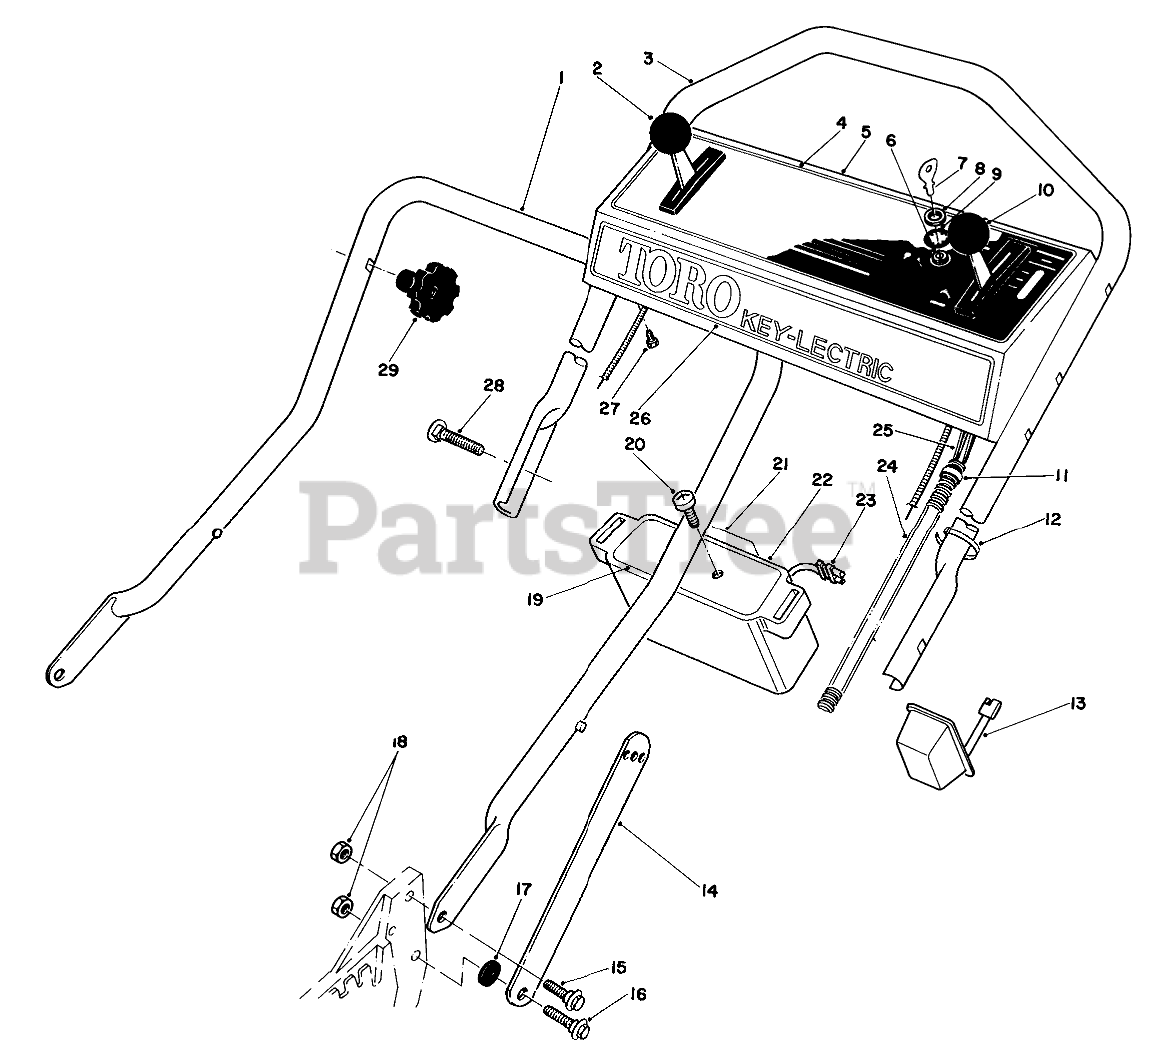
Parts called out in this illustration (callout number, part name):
1	Handle-Lower
2	GROUND SPEED CONTROL
3	Handle-Upper
4	Decal-Instruction Panel
5	Control Panel (Incl Ref. #4)
6	STARTER SWITCH ASM
7	Key
8	NUT-HH
9	WASHER-TOOTH, INTERNAL
10	SERVICE THROTTLE CONTRO
11	FITTING-RING
12	TIE-CABLE
13	Charger
14	Handle Latch
15	SCREW-SHOULDER
16	SCREW-SHOULDER
17	SPACER
18	NUT-LOCK, NI
19	BATTERY COVER
21	Decal
22	Battery Case
23	LEAD WIRE ASM
24	CONTROL CABLE COVER
25	WIRE HARNESS
26	Decal-Toro
27	SCREW-HWHTF
28	5/16-18 X 2 HNDLE SCREW
